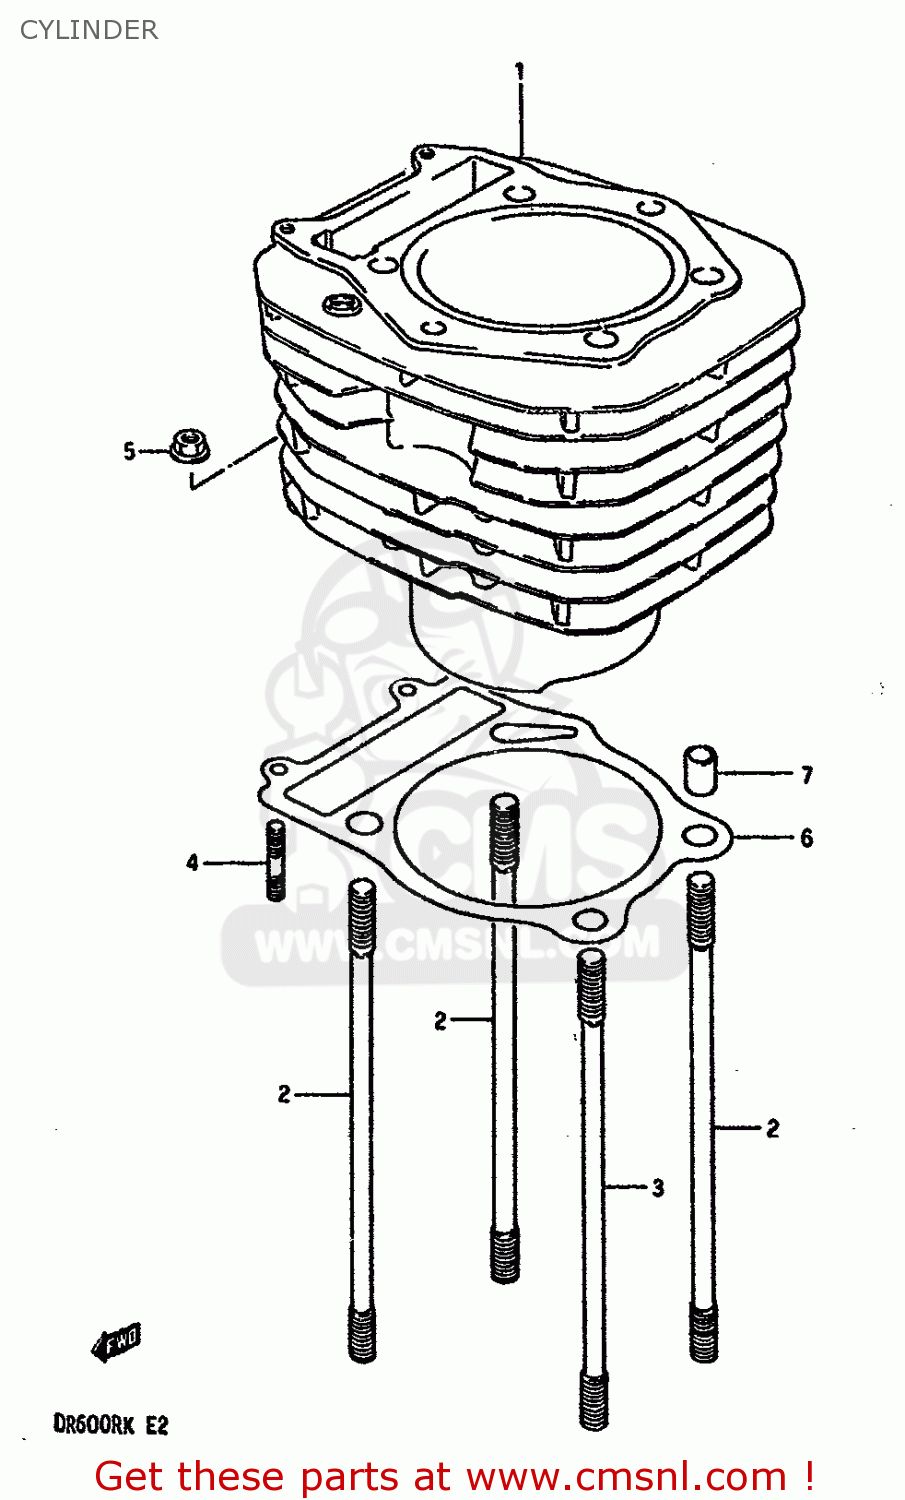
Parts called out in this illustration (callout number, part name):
1	CYLINDER
2	STUD
3	STUD
4	STUD BOLT L:20
5	NUT 6MM
6	GASKET,CYLINDER (MCA)
7	PIN
